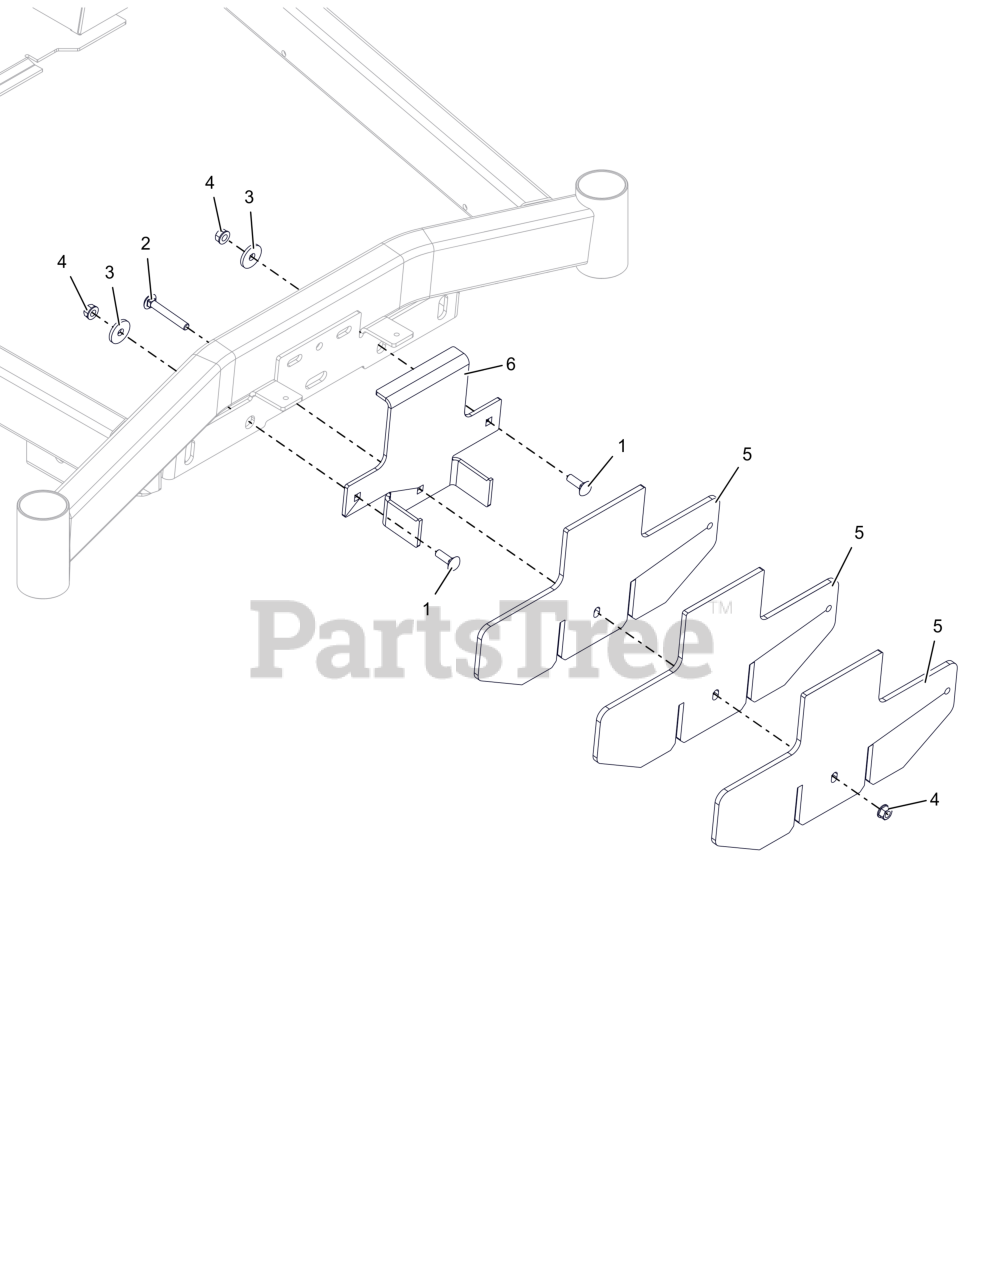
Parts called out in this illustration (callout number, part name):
1	BLT,RHSN .31-18X1.00 G5 ZCC
2	BLT, RHSN .31-18X2.25 G5 ZCC
3	WSHR, FLT .340X1.125X.135 ZCC
4	NUT,LK-CTR-FLG .31-18 GF ZCC
5	PLATE, BAGGER WEIGHT (BLACK)
6	BRKT, BAGGER WEIGHT MTG (BLACK)
